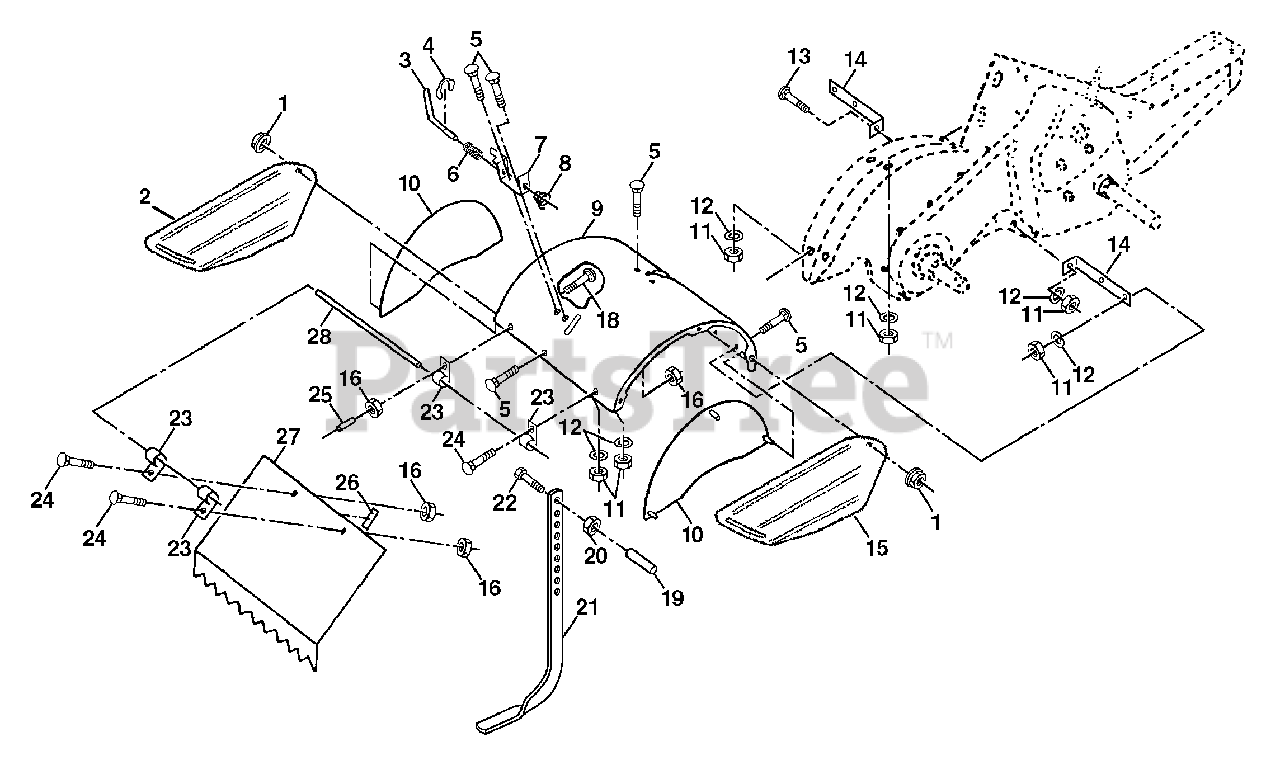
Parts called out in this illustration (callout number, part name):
1	Nut, Flange 5/16-18
2	Shield, Side, Outer L. H.
3	Pin, Stake, Depth
4	Ring, Klip
5	Bolt, Carriage 5/16-18 x 3/4 Gr. 5
7	Bracket, Latch
8	Spring, Depth Stake
9	Shield, Tine
10	Bolt, Carriage 5/16-18 UNC x 1
11	Nut, Hex 5/16-18
12	Washer, Lock 5/16
13	Bolt, Carriage 5/16-18 x 1-1/4
14	Bracket, Shield Tine
15	Shield, Side, Outer R.H.
16	Nut, Keps Hex 1/4-20
18	Bolt, Carriage 1/4-20 x 1-1/4 Gr. 5
20	Nut, Hex 3/8-16
21	Stake, Depth
22	Bolt, Hex 3/8-16 x 2
24	Bolt, Carriage 1/4-20 x 1/2 Gr. 5
25	Cap, Vinyl
26	Pad, Idler
27	Shield, Leveling
28	Pin, Hinge
29	Shield, Side
30	Locknut, Flange 5/16-18
